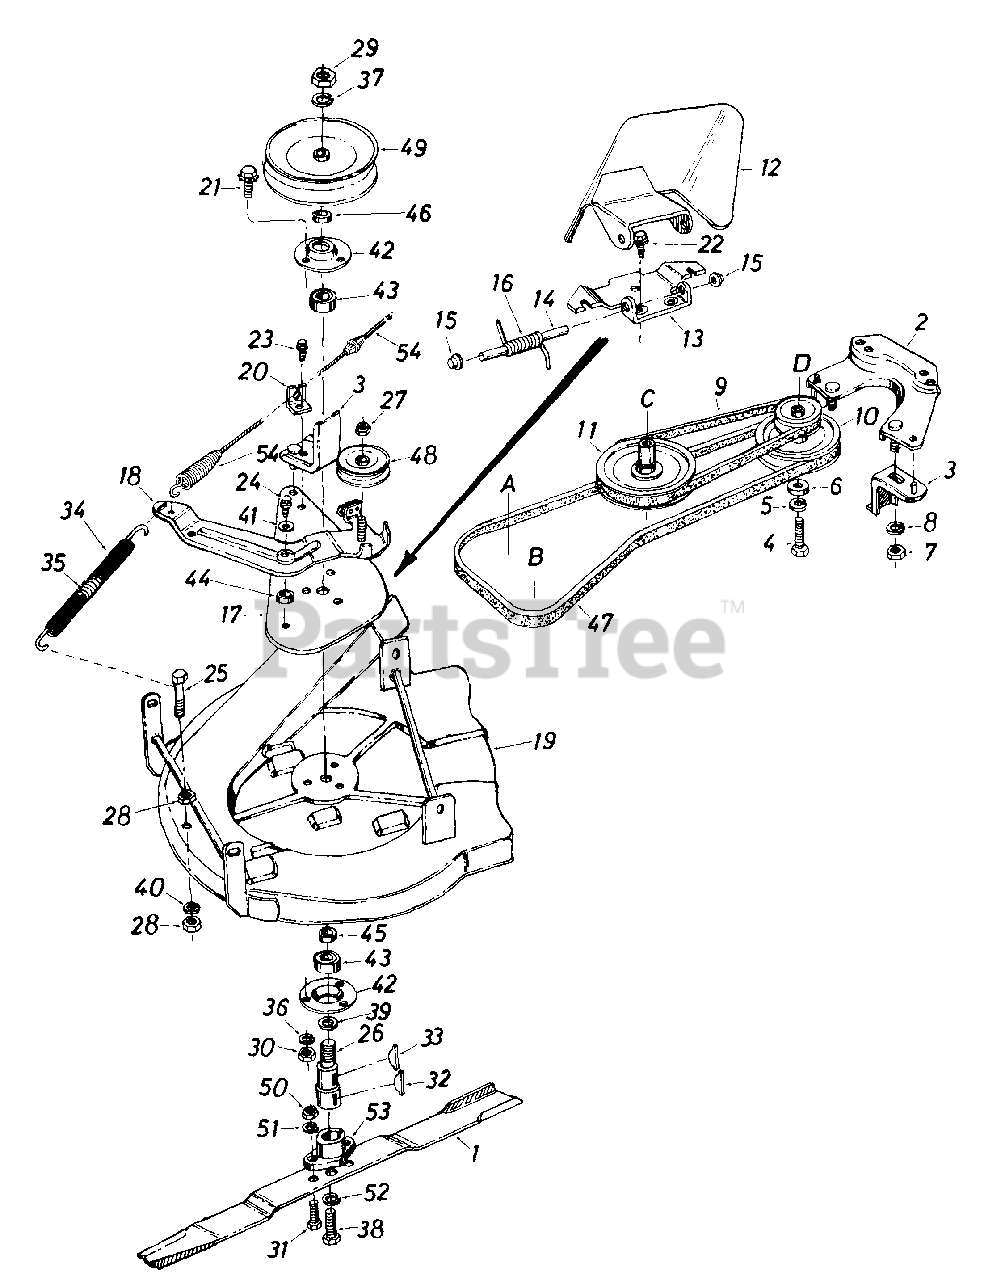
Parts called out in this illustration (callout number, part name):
1	26" Blade
2	Belt Guard Cup Ass'y.
3	Belt Keeper Ass'y.
4	Hex Bolt 3/8-24 x 1.00" Lg.
5	L-Wash. 3/8" I.D.
6	Fl-Wash. .406" I.D. x 1.25"
7	Hex Nut 5/16-18 Thd.
8	L-Wash. 5/16" I.D.
9	3V-Belt 28" Lg.
10	Double Pulley
11	3/8" V-Pulley .502" I.D. x 6.5" O.D.
12	Chute Cover Ass'y. Comp.
13	Adapter Plate
14	Hinge Pin
15	Cap Speed Nut 1/4" Rod
16	Torsion Spring
17	Deck Belt Guard Plate
18	Deck Idler Brkt. Ass'y.
19	26" Deck Ass'y.
20	Cable Support Brkt.
21	Hex Sems Bolt 5/16-18 x 1.00" Lg.
22	Hex Wash. S-Tap Scr. 1/4-20 x .50" Lg.
23	Hex Wash. Hd. B-Tap Scr. 5/16-18 x .50" Lg.
24	Hex L-Bolt 5/16-18 x 1.00" Lg
25	Hex Bolt 1/4-28 x 1.50" Lg.
26	Blade Spindle
27	Hex Ins. L-Nut 3/8-24 Thd.
28	Hex Cent. L-Nut 1/4-28 Thd.
29	Hex Jam Nut 5/8-11 Thd.
30	Hex Nut 5/16-18 Thd.
31	Hex Bolt 5/16-24 x 1.00" Lg. (Grade 5) Special
32	#6 Hi-Pro Key 5/32 x 5/8" Dia
33	#61 Hi-Pro Key 3/16" x 5/8" Dia.
34	Plastic Tube .52" I.D. x 7.0" Lg.
35	Ext. Spring .50" I.D. x 5.2" Lg.
36	L-Wash. 5/16" I.D.
37	L-Wash. 5/8" I.D.
38	Hex Bolt 3/8-24 x 1.50" Lg. (Grade 5)
39	Bearing Shield
40	L-Wash. 1/4" I.D.
41	Fl-Wash. .330" I.D. x 1.25" O.D. x .120
42	Bearing Housing
43	Ball Brg. .787" I.D. x 1.85" O.D.
44	Spacer .315" I.D. x .75" O.D. x .37" Lg.
45	Spacer .836" I.D. x 1.01" O.D x .320" Lg.
46	Spacer .630" I.D. x 1.135" O.D. x .195" Lg.
47	"V"-Belt-A Sec. x 59.0" Lg.
48	"V"-Idler 3.06" O.D.
49	5/8" V-Pulley .625" I.D. x 7.0" O.D.
50	Hex Nut 5/16-24 Thd.
51	L-Wash. 5/16" I.D.
52	L-Wash. 3/8" I.D. - Heavy Duty
53	Blade Adapter Kit
54	Clutch Cable - 56" Lg.
